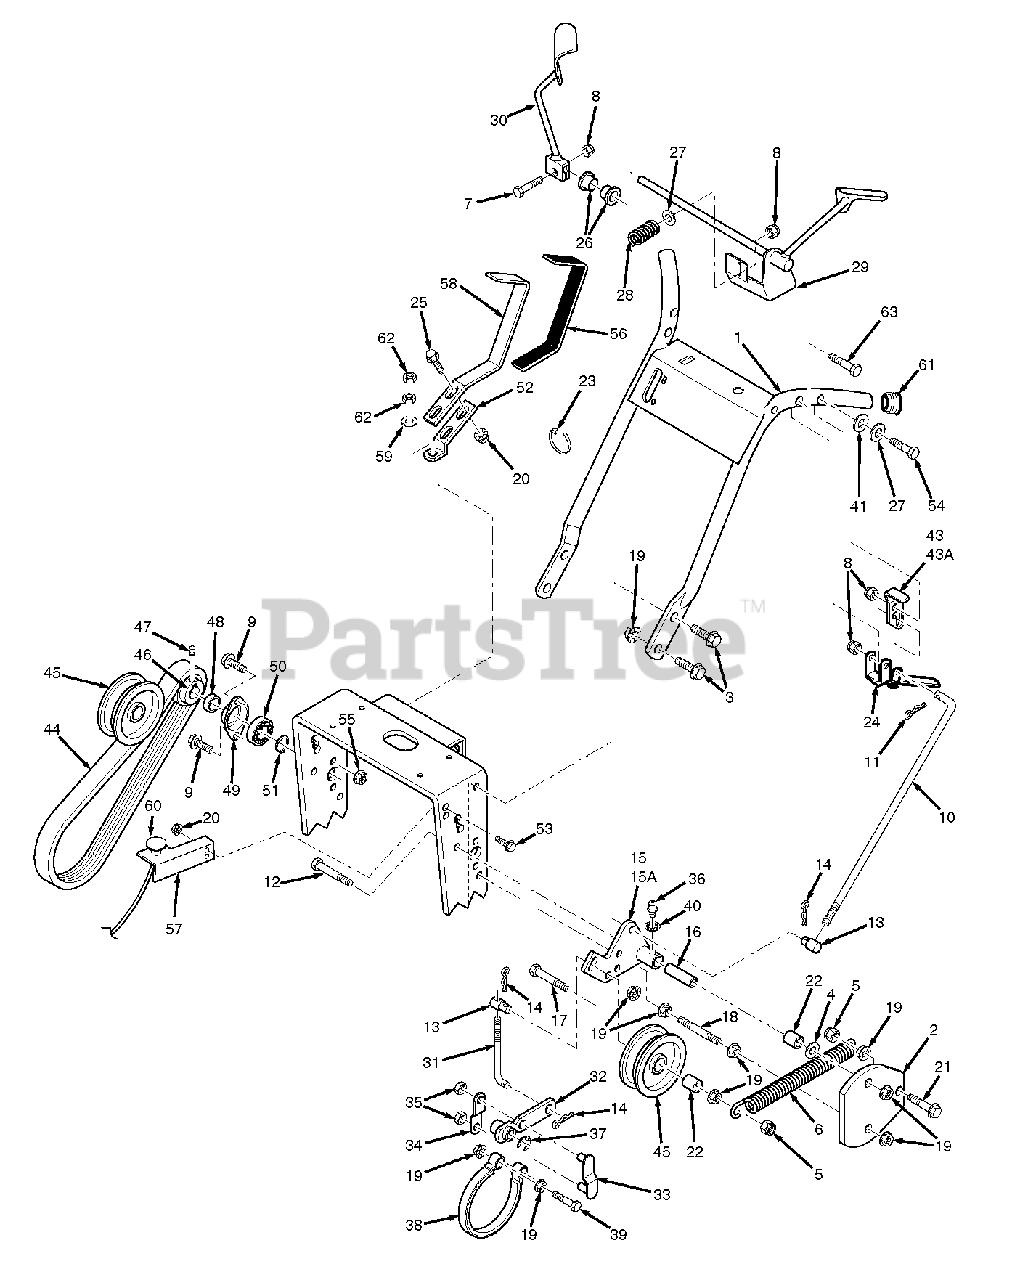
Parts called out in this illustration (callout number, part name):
1	Handle Assembly
2	Belt Guard
3	Capscrw, 3/8-16 x 1" Serr. Flg.
4	Washer, 3/8" (.391 x .938 x .105)
5	Nut, 3/8-16 Elastic Stop
6	Spring, Idler
7	Bolt, 5/16-18 x 1-1/4" Hex Head
8	Nut, 5/16-18 Elastic Stop
9	Capscrew, 1/4-20 x 3/4" Hex Head
10	Control Rod, Steering
11	Hair Pin, Small
12	Bolt, 3/8-16 x 4-1/2" Hex Head
13	Swivel Joint
14	Hair Pin, Large .094 Dia.
15	Idler Bracket, RH
15A	Idler Bracket, LH
16	Idler Sleeve
17	Bolt, 3/8-16 x 3/4" Hex Head
18	Stud, 3/8-16 x 5"
19	Nut, 3/8-16 Serrated Flange
20	Nut, 5/16-18 Serrated Flange
21	Cpscrw, 3/16-18 x 1-1/4" Serr. Flg
22	Spacer
23	Cable Tie
24	Steering Lever
25	Capscrew, 5/16-18 x 1" Serr. Flg.
26	Bushing
27	Washer, 5/16 (.375 x .875 x .083)
28	Spring, Operator Presence
29	Operator Presence Lever, LH
30	Operator Presence Lever, RH
31	Brake Rod
32	Brake Lever
33	Brake Link
34	Brake Link Plate
35	Nut, 3/8 Push-on
36	Grease Fitting, Straight 1/4-28
37	Retaining Ring, 5/8 Ext. "E"
38	Brake Band
39	Bolt, 3/8-16 x 2" Hex Head
40	1/4" Internal Tooth Lockwasher
41	Socket Head Capscrew #8-32 x 1/2"
42	Socket Head Capscrew #8-32 x 1/2"
43	Neutral Latch, RH
43A	Neutral Latch, LH
44	Belt, Wheel Drive
45	Idler Pulley, Wheel Drive
46	Pulley, Jackshaft
47	Setscrew, Hex Socket Knurl Cup Pt. 5/16-18
48	Spacer, Jackshaft Pulley
49	Flange, Jackshaft Bearing
50	Bearing, Jackshaft
51	Retaining Ring, 5/8 Ext. Basic
52	Shift Lever
53	Capscrew, 5/16-18 x 3/4" Serr. Flg.
54	Bolt, 5/16-18 x 2" Hex Head
55	Nut, 1/4-20 Serrated Flange
56	Grip, Shift Handle
57	Bracket, Choke Mounting
58	Shift Lever Extention
59	Washer, 3/8 (.391x .938 x .105)
60	Choke Control
61	Plug, Handlebar
62	Nut, 3/8-24 UNF
63	Bolt, 5/16-18 x 2-1/2"
64	Fuel Tank Cap
